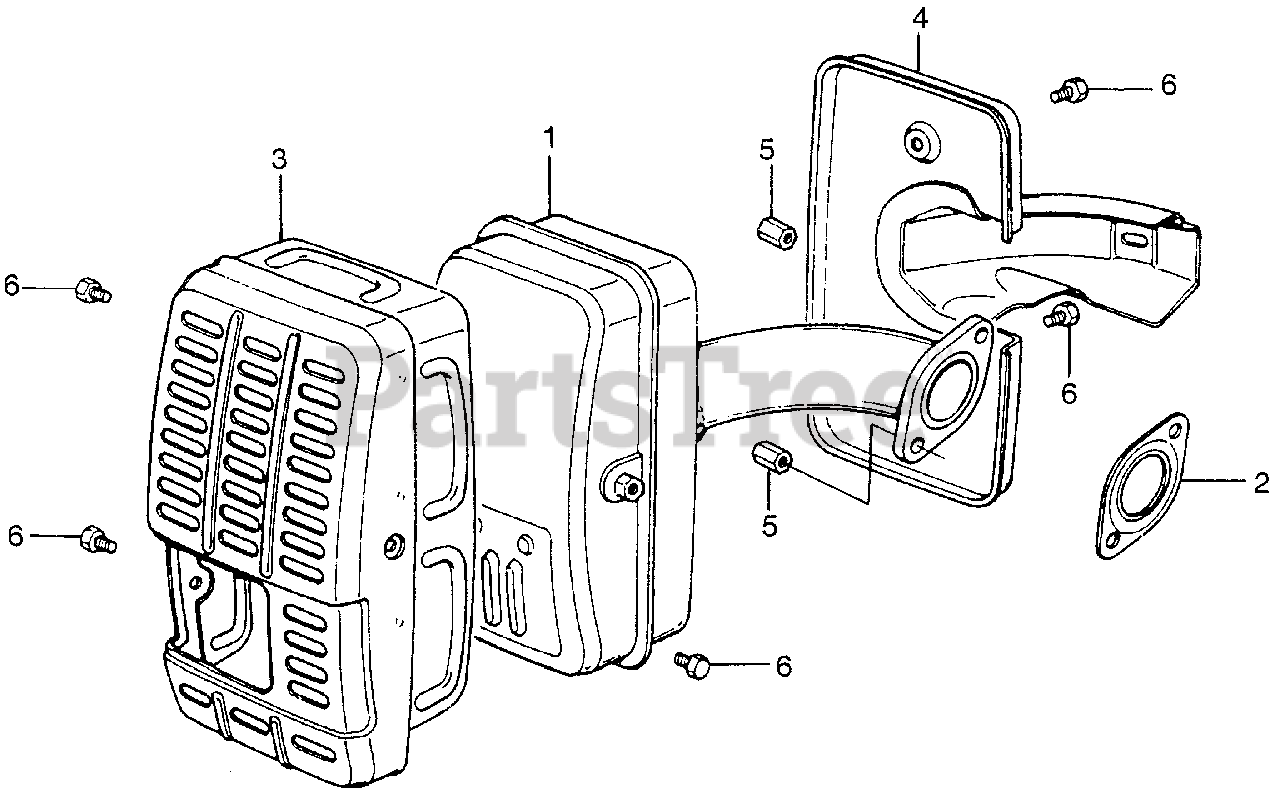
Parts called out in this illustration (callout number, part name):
1	MUFFLER (NOT AVAILABLE)
2	GASKET, MUFFLER (NOT AVAILABLE)
3	PROTECTOR, MUFFLER
4	SEPARATOR, MUFFLER
5	NUT, HEX. (6MM)
6	BOLT, HEX. (6X6)
